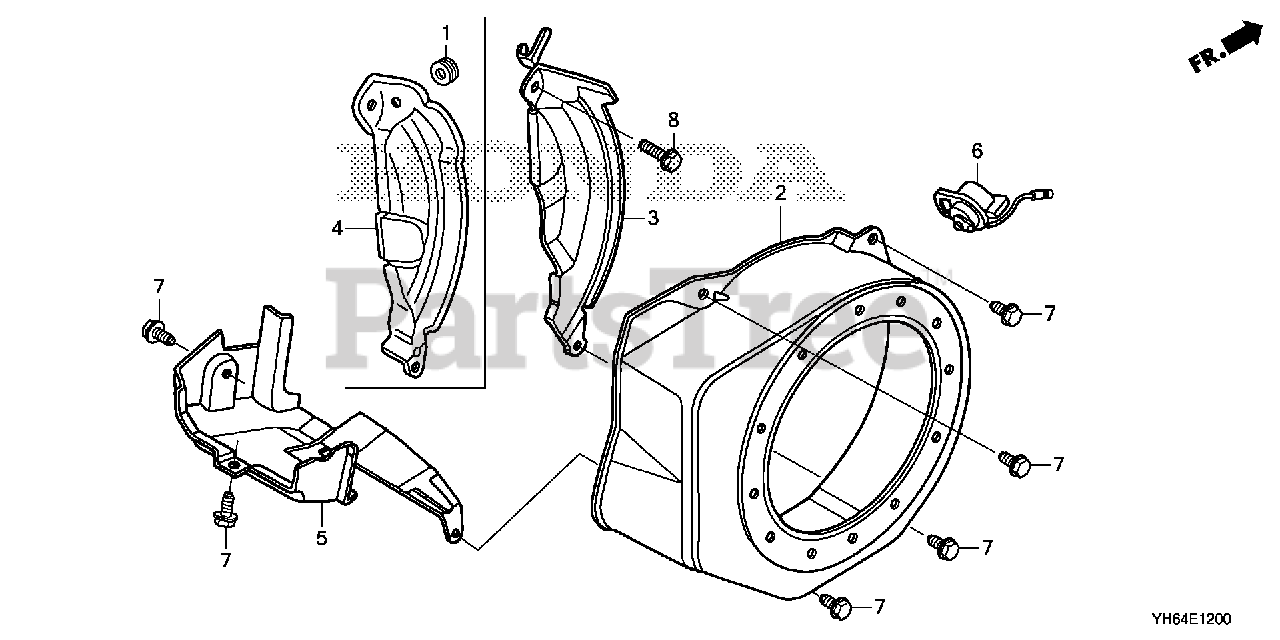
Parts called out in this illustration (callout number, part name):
1	GROMMET, ADJUSTING COVER
2	COVER, FAN *R280* (POWER RED)
4	PLATE, SIDE (STD)
6	SWITCH ASSY., ENGINE STOP (TOYO DENSO)
6	SWITCH ASSY., ENGINE STOP (MINDA)
7	BOLT, FLANGE (6X12) (CT200)
8	BOLT, FLANGE (6X20) (CT200)
